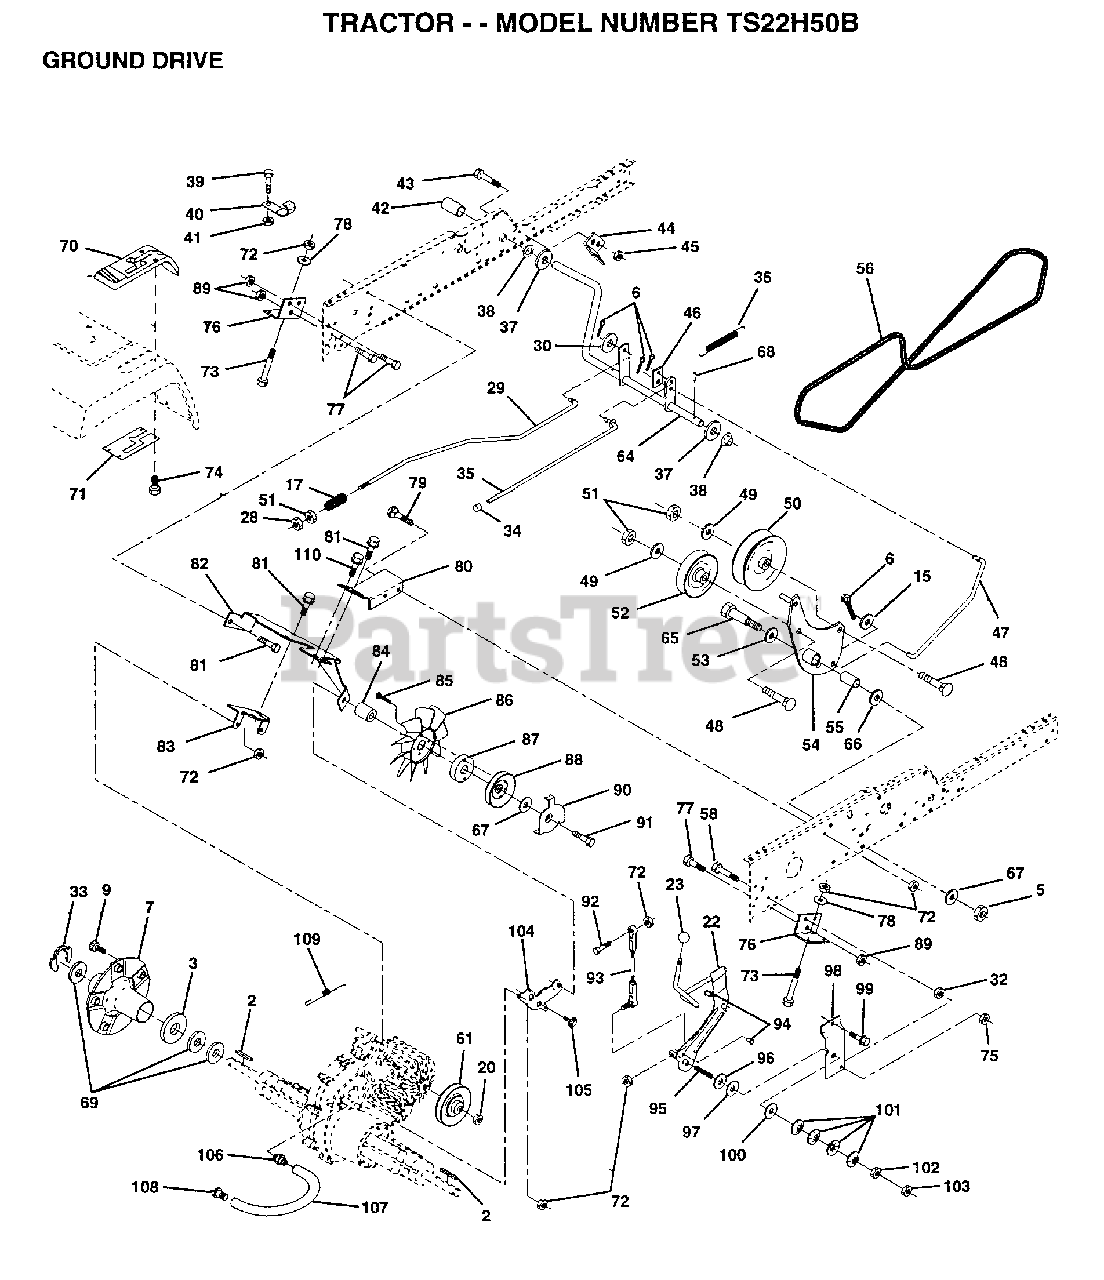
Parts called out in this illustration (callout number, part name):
2	KEY 1/4 X 2.5
3	WASHER T
6	COTTER PIN
7	HUB WHEEL ASM
9	BOLT.HUB.WHL.REAR
15	WASHER
17	SPRING ROD BRAKE
22	SHAFT ARM ASM
23	KNOB.DUCKHEAD.1/2
28	NUT
29	ROD BRAKE
30	WASHER
32	NUT
33	E RING HYT
34	PLUNGER CAP T
35	ROD BRAKE PART GT
36	SPRING.GRND.DRIVE
37	WASHER
38	BUSHING.NYLINER
39	SCREW
40	ACT-SWITCH T
42	PEDAL COVER T
43	BOLT LT
44	BRKT SWITCH GT
45	NUT
46	RETAINER.SPRING
47	ROD.CLUTCH
48	BOLT
49	WASHER
50	FLAT IDLER PULLEY
51	NUT
52	PULLEY.IDLER.V.GR
53	WASHER T
54	ARM.ASM.IDLER.CLU
55	"LY, BEARING"
56	BELT-V 84.5
58	BOLT
61	PULLEY TRANSAXLE
64	SHAFT-BRAKE/CLUTC
65	AXLE BOLT
66	WASHER.HARD.BLADE
67	WASHER
68	ROLL PIN STD
69	WASHER
71	"PLATE CONSOLE,SFT"
72	NUT
73	BOLT FIN HEX 5/16
74	SCREW HEXWSH H-L
75	NUT.7/16
76	BRACKET TRAN VGTH
77	BOLT
78	WASHER
79	BOLT
80	BRACKET TORQUE RH
81	SCREW
82	BRACKET.MTG.FAN
83	STRAP TORQUE MID
84	SPACER
85	SCREW YTV
86	"FAN 7"" HYDRO"
87	ADAPTER FAN
89	NUT GTV
90	KEEPER BELT
91	SCREW.HXWSH.3/8
93	LINK ASM SHIFT
94	XMAS TREE FASTNER
95	SCREW SET 5/16
96	WASHER NICKEL PLT
97	BEARING THRUST
98	BRACKET SHIFT
99	SCREW LT
100	WASHER COMPRESSIN
101	WASHER
102	NUT HEX NYLOCK
103	JAM NUT TI
104	BRACKET IDLER
105	SCREW CRT
106	O-RING.ASM.70110
107	"LINE FUEL,HYD 15"""
108	CAP.VENT.70109
109	SPRING BRAKE
110	HINGE SCREW
